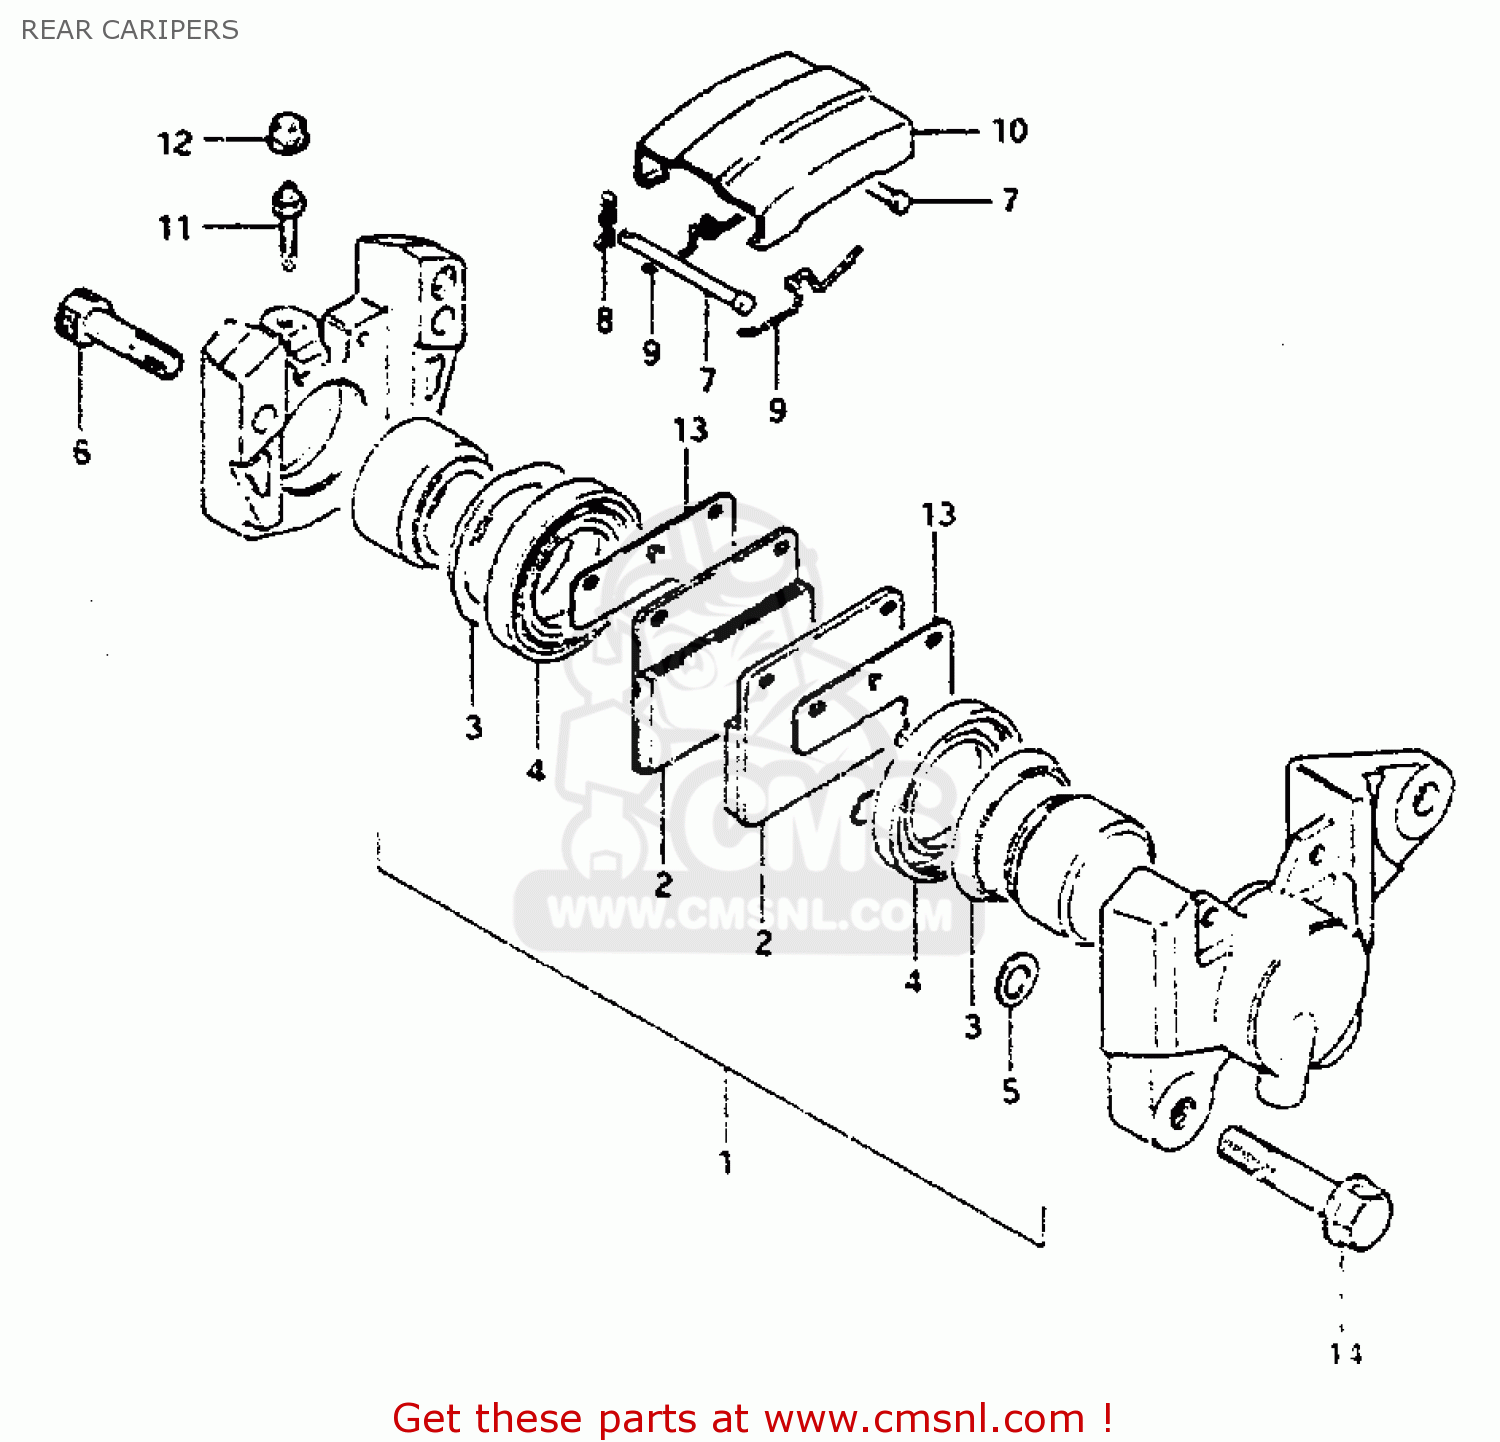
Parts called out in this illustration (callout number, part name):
1	PISTON SET
2	PAD,BRAKE
3	SEAL,PISTON
4	BOOT,PISTON
5	SEAL,JOINT
6	BOLT,CALIPER HOUSING
7	PIN,PAD
8	CLIP,PAD PIN
9	SPRING
10	COVER,DUST
11	BLEEDER
12	CAP,BREATHER
13	SHIM,RR CALIPER
14	BOLT
